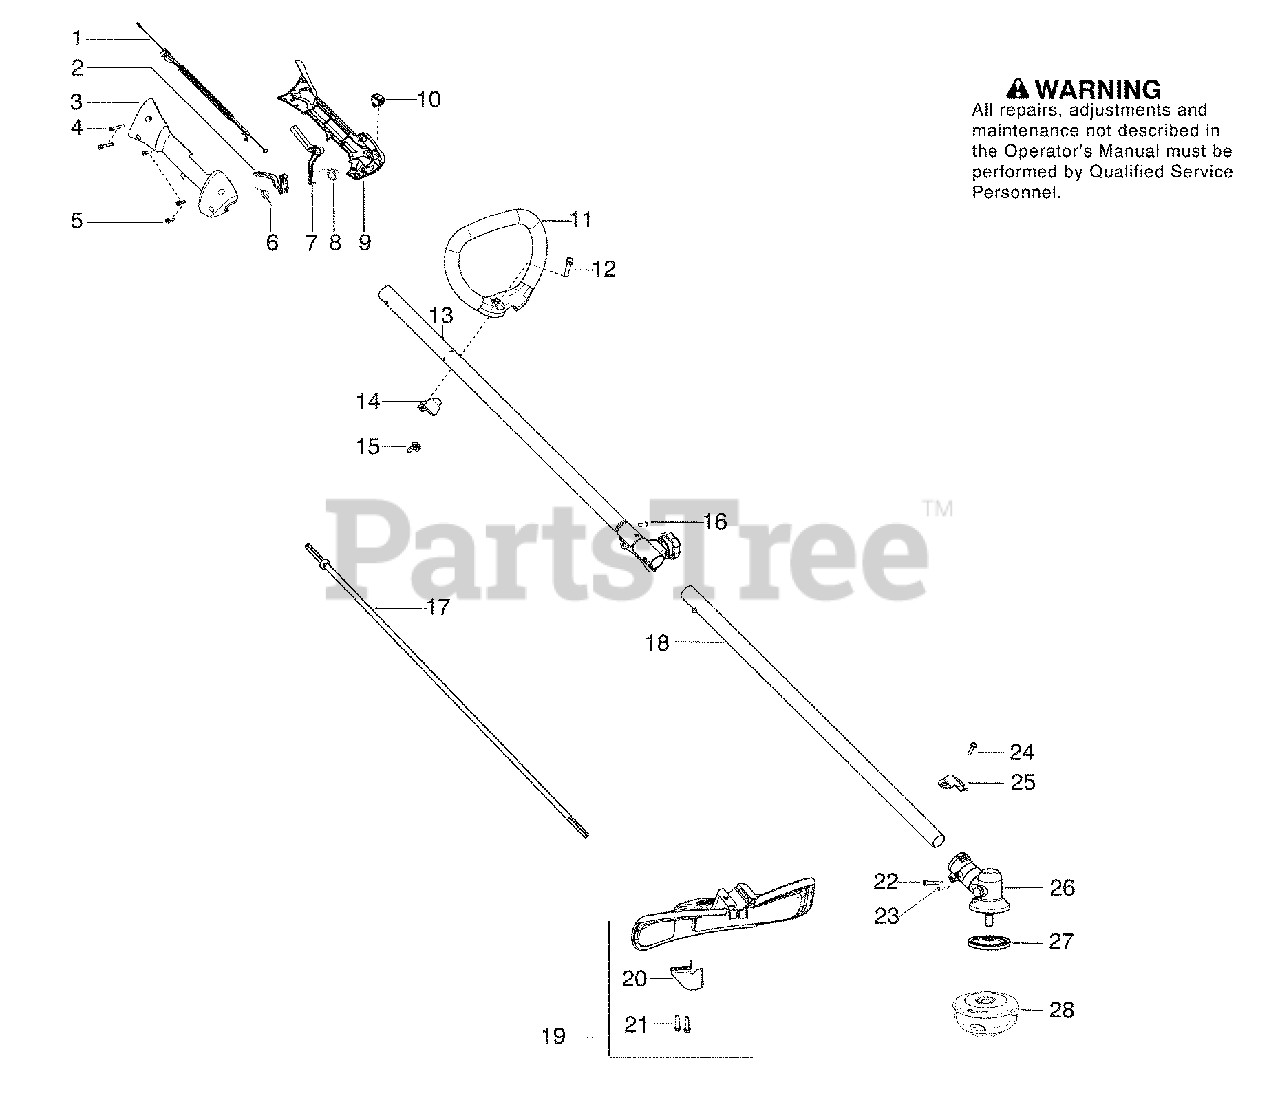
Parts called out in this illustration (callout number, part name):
1	Assy - Cable/Wire Harness
3	Housing – Throttle
6	Spring - Trigger
7	Lockout - Throttle
8	Spring - Lockout
9	Housing – Throttle
10	Kit - Switch
11	Handle - Assist
13	Kit - Driveshaft Upper
14	Clamp - Handle Assist
15	Wingnut
18	Kit - Lower Shaft
19	Kit – Shield
20	Limiter - Line
25	Bracket - Shield
26	Assy - Gearbox
27	Driver Disc
28	Assy - T25 Cutting Head
